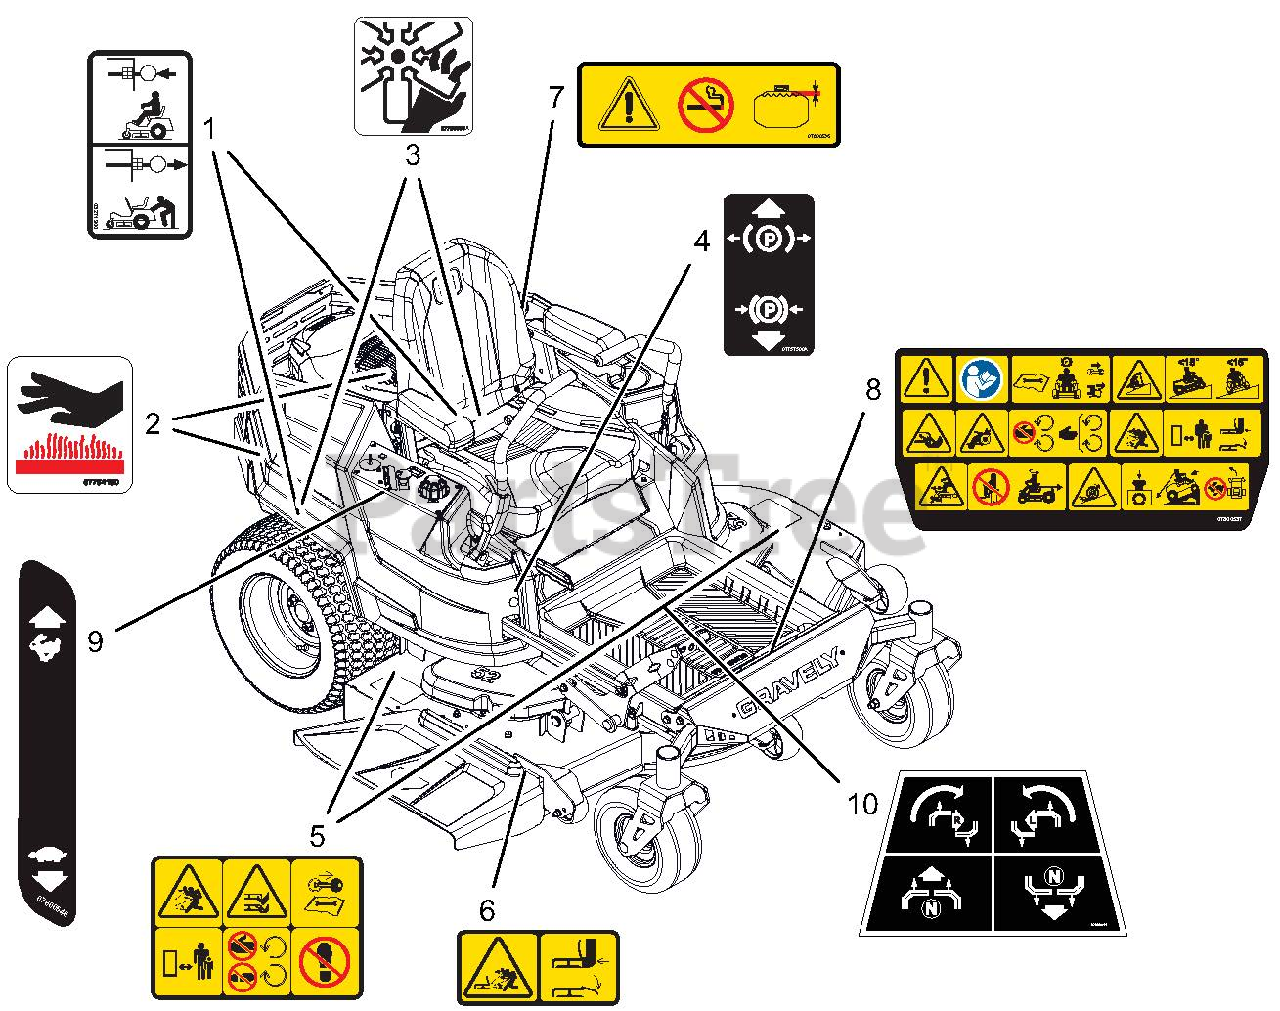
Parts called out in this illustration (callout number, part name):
1	DECAL, TRANSMISSION DISCONNECT
2	DECAL HOT SURFACE
3	DECAL, DANGER - FAN
4	DECAL, PARKING BRAKE LEVER
5	DECAL, SAFETY - MOWER DECK
6	DECAL, SAFETY - DECK GUARDING
7	DECAL, FUEL WARNING
8	DECAL, MAIN SAFETY-IKON ZTX
9	DECAL, DASH
10	DECAL, STEERING
